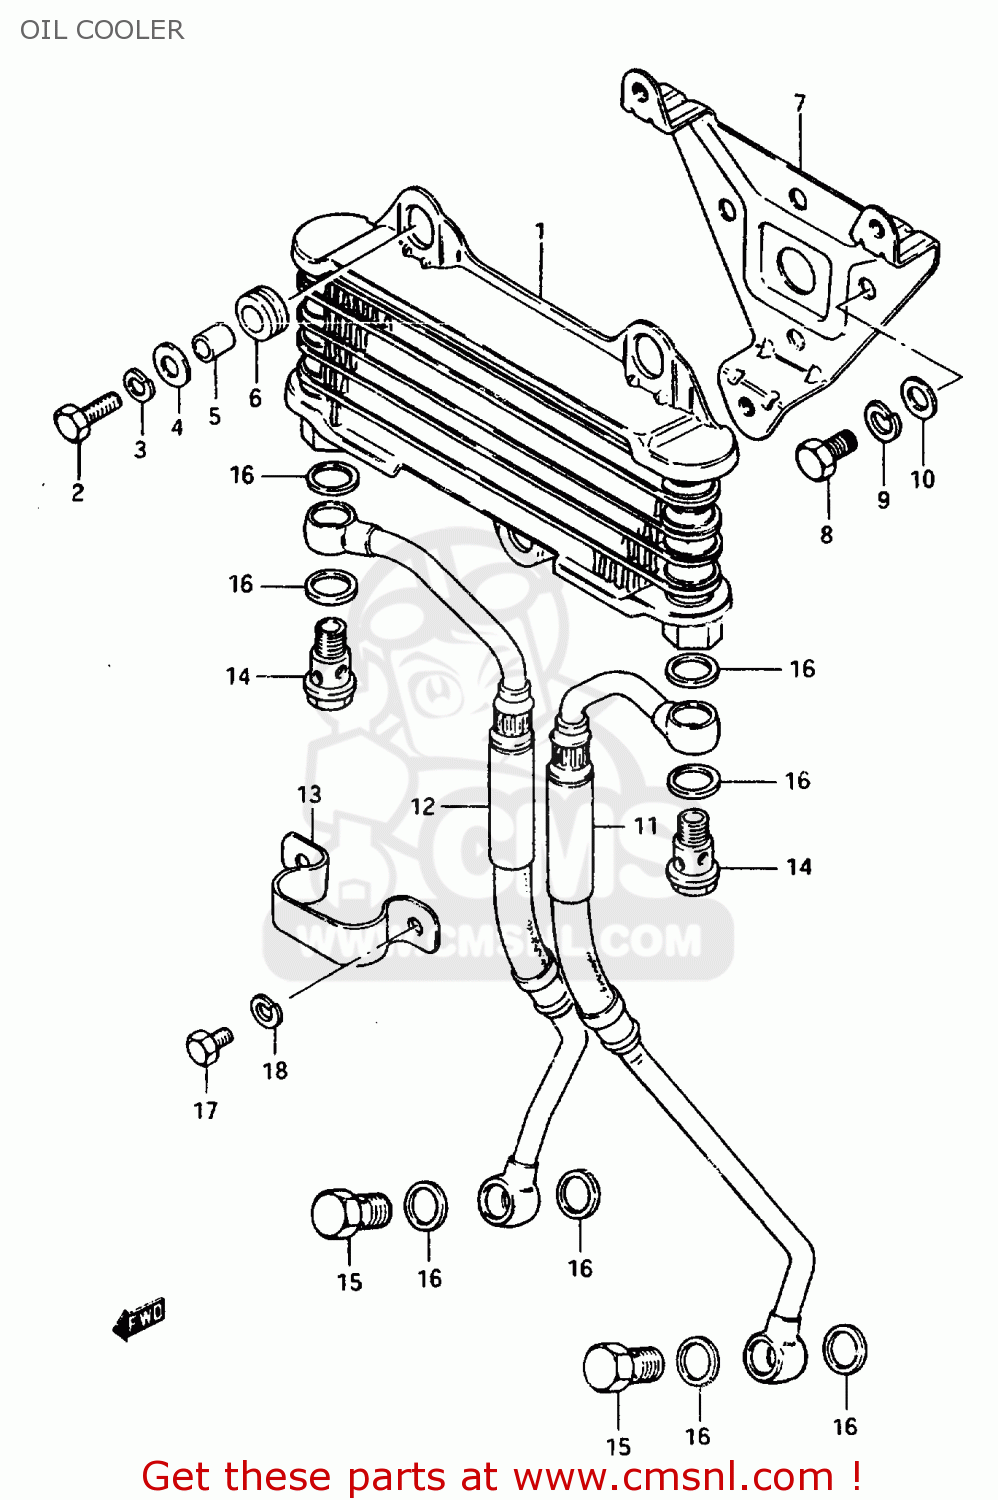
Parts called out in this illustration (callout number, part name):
1	COOLER ASSEMBLY,ENGINE OIL
2	BOLT
3	WASHER,LOCK
4	WASHER (6.5X18X1.6)
5	SPACER (6.8X10X10)
6	CUSHION
7	BRACKET,OIL COOLER
8	BOLT
9	LOCK WASHER
10	WASHER,8.5X16X
11	HOSE,ENGINE OIL,LEFT
12	HOSE,ENGINE OIL,RIGHT
13	CLAMP,OIL HOSE
14	BOLT UNION
15	BOLT UNION
16	GASKET(14X20X1.5) (NAS)
17	BOLT
18	WASHER,LOCK
